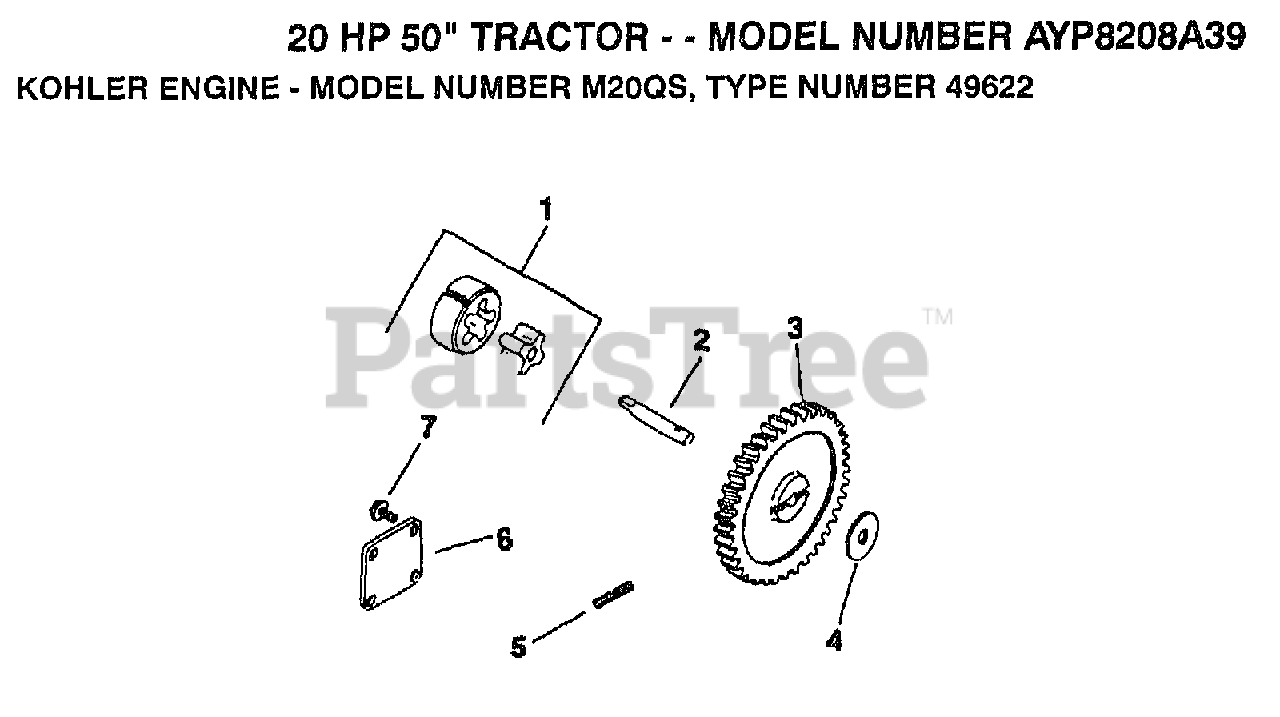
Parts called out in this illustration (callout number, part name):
2	SHAFT, OIL PUMP
3	GEAR, OIL PUMP
4	SPACER, SHIM
5	PIN, ROLL
6	COVER, OIL PUMP
7	SCREW
